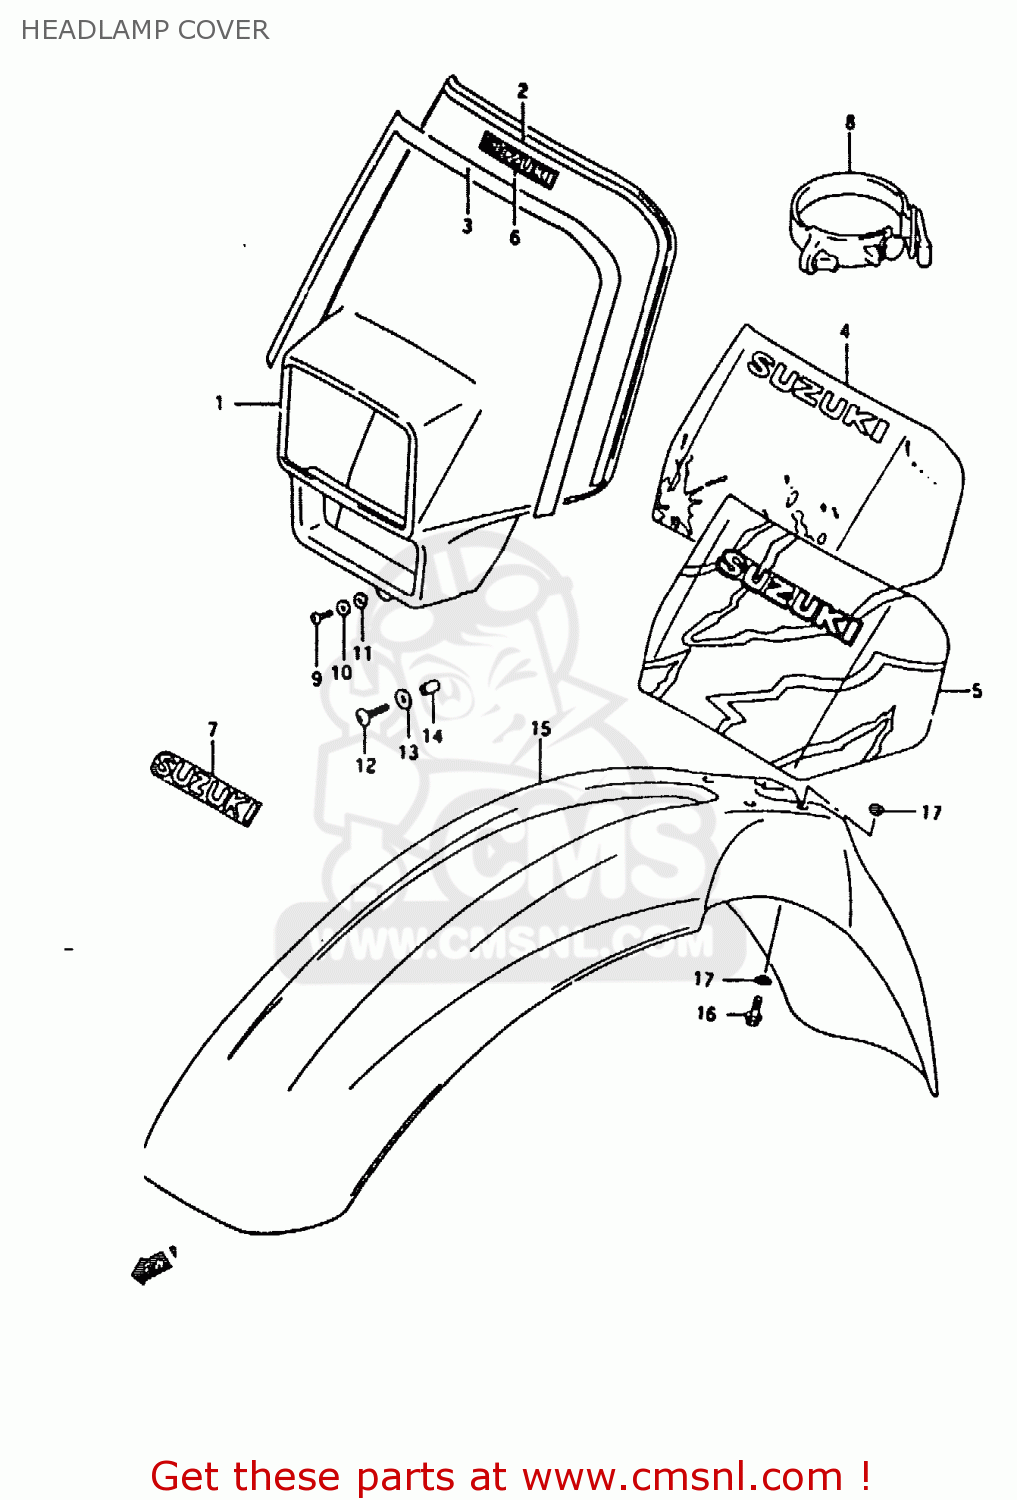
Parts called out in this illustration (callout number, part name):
1	COVER, HEADLAMP (YELLOW)
2	TAPE,HEADLAMP HOUSING
3	TAPE,HEADLAMP COVER
4	TAPE,HEADLAMP COVER
5	TAPE,HEADLAMP COVER
6	EMBLEM,HEADLAMP HOUSING
7	EMBLEM,HEADLAMP COVER
8	BAND,HEADLAMP COVER
9	SCREW
10	WASHER (5.5X16X1.2)
11	WASHER
12	SCREW
13	WASHER
14	SPACER(6.2X12X16)
15	FENDER,FRONT
16	BOLT
17	WASHER
